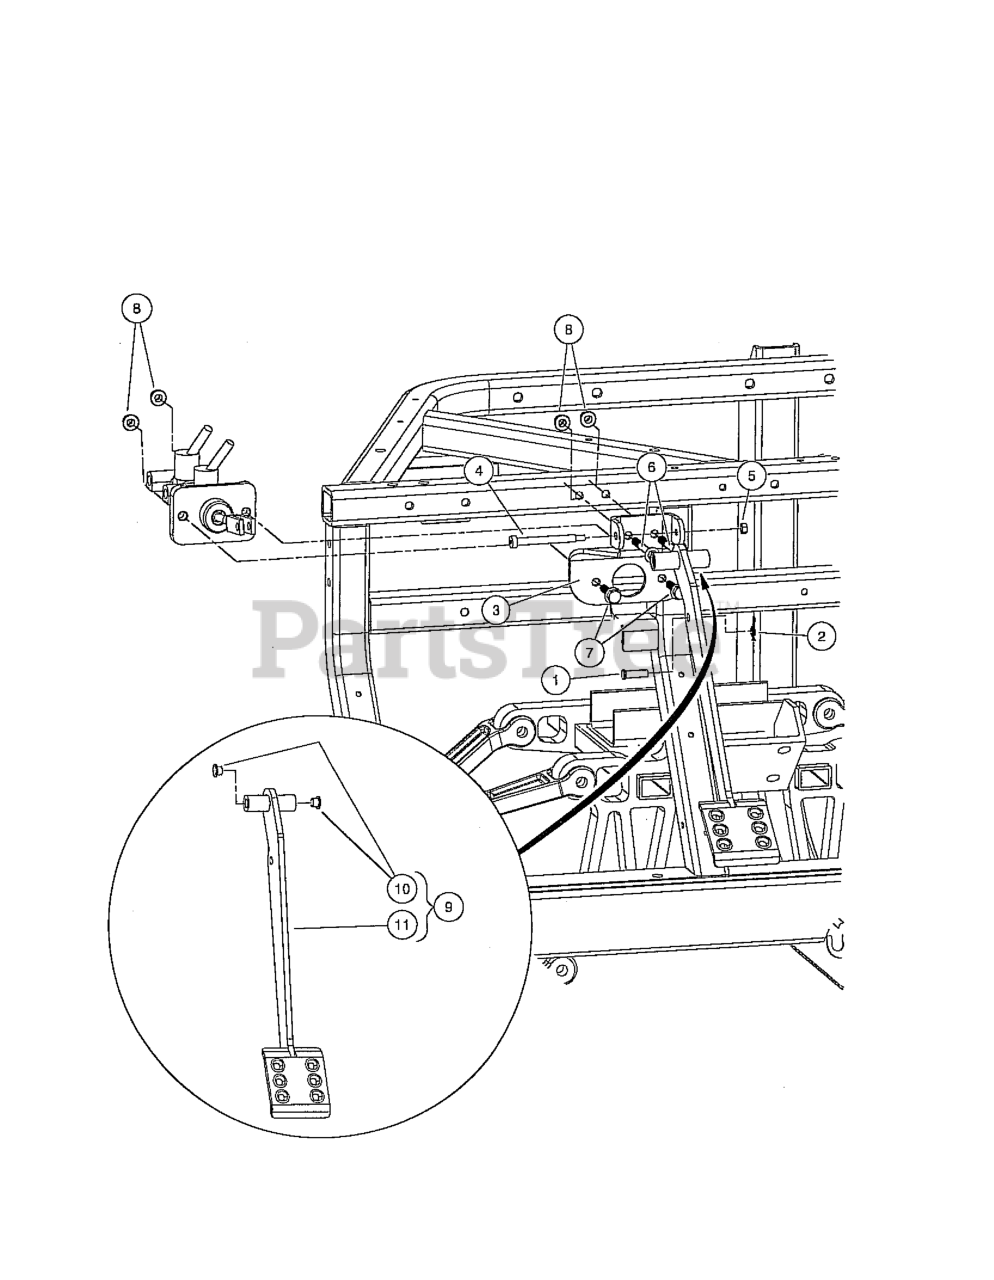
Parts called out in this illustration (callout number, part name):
1	CLEVIS PIN, 5/16 X 1
3	BRACKET, PEDAL, BRAKE
4	BOLT, SHOULDER, M8 X 70
5	NUT M6X1 MECH DEF CENTER
6	BOLT FLG, M8X1.25X65
7	BOLT FLG, M8X1.25X35
8	LOCK NUT, FLG M8 X 1.25 NYLON
10	BUSHING, GREASELESS
11	WELDMENT, PEDAL, BRAKE, HUNG
